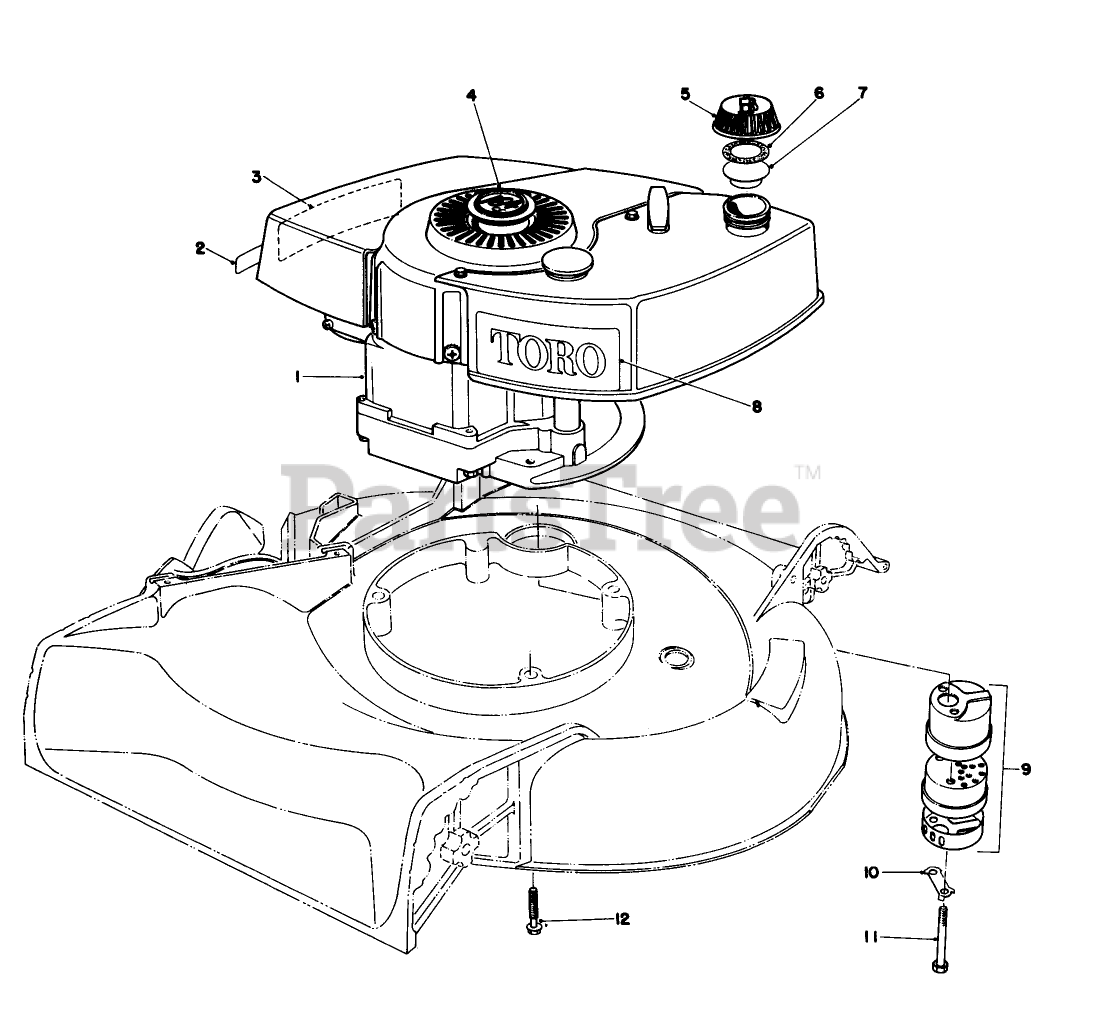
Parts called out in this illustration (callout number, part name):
1	Engine
2	Decal-Primer Bulb
3	Decal Maintenance
4	Plug Button
5	Gas Cap Assembly (Incl. Ref. #6&7)
6	GASKET
7	GAS CAP BAFFLE
8	Decal Toro
9	Muffler (Incl. Ref. #10 & 11)
10	CLIP - LOCKING
11	SCREW-HH
12	Screw
